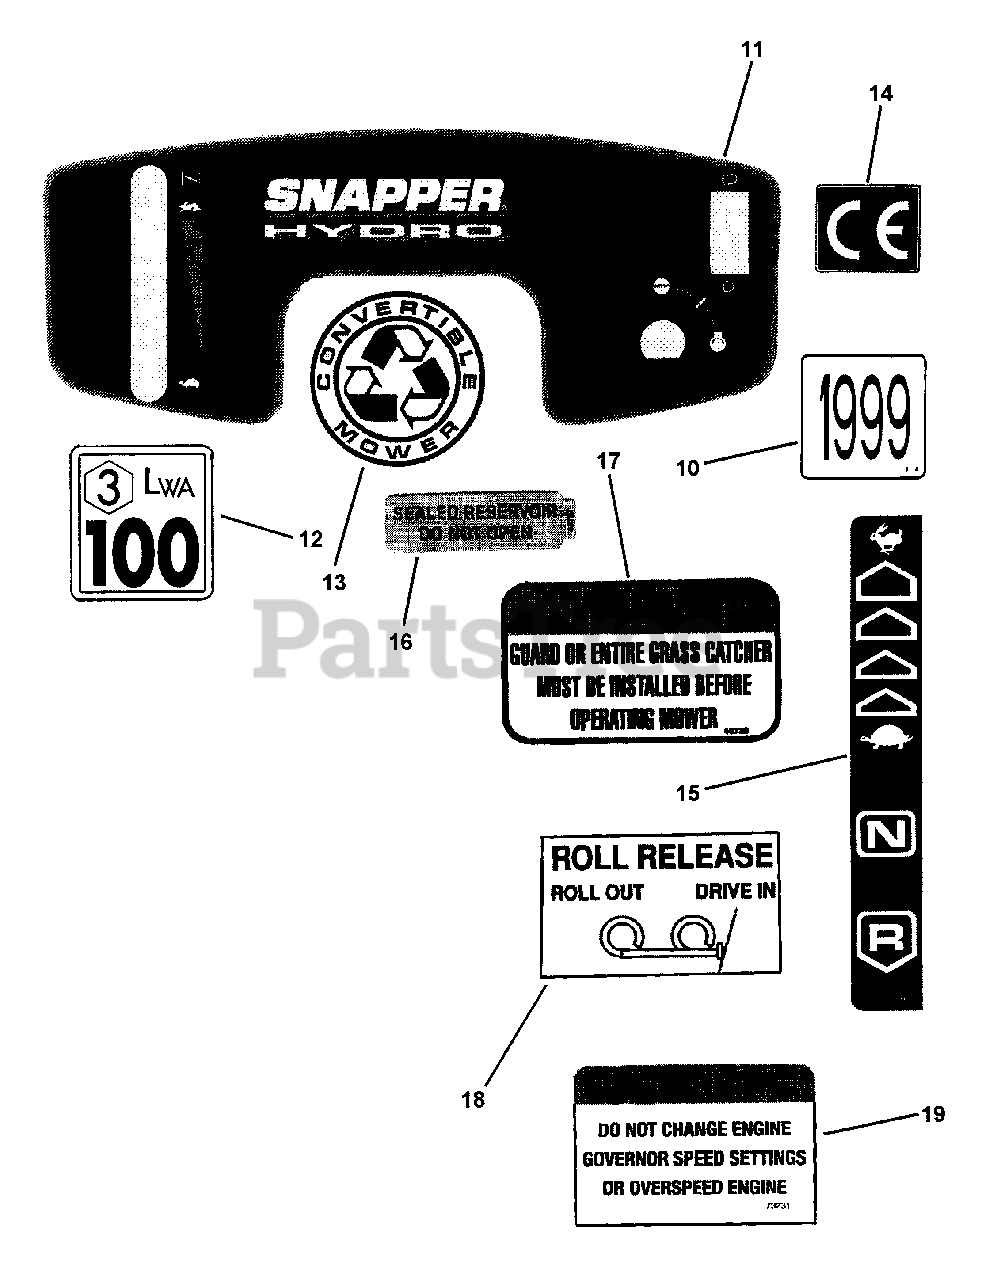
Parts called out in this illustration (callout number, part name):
10	DECAL, 1999 Year of Manufacture
11	DECAL, Console, Basic
12	DECAL, Noise Control, Euro
13	LOGO, Convert- Blue/Silver
14	DECAL, European Community
15	DECAL, Shift Cover
16	DECAL, Hydro Reservoir
17	DECAL, Chute/Deflector
18	DECAL, Roll Release
19	DECAL, Warning Speed Setting
